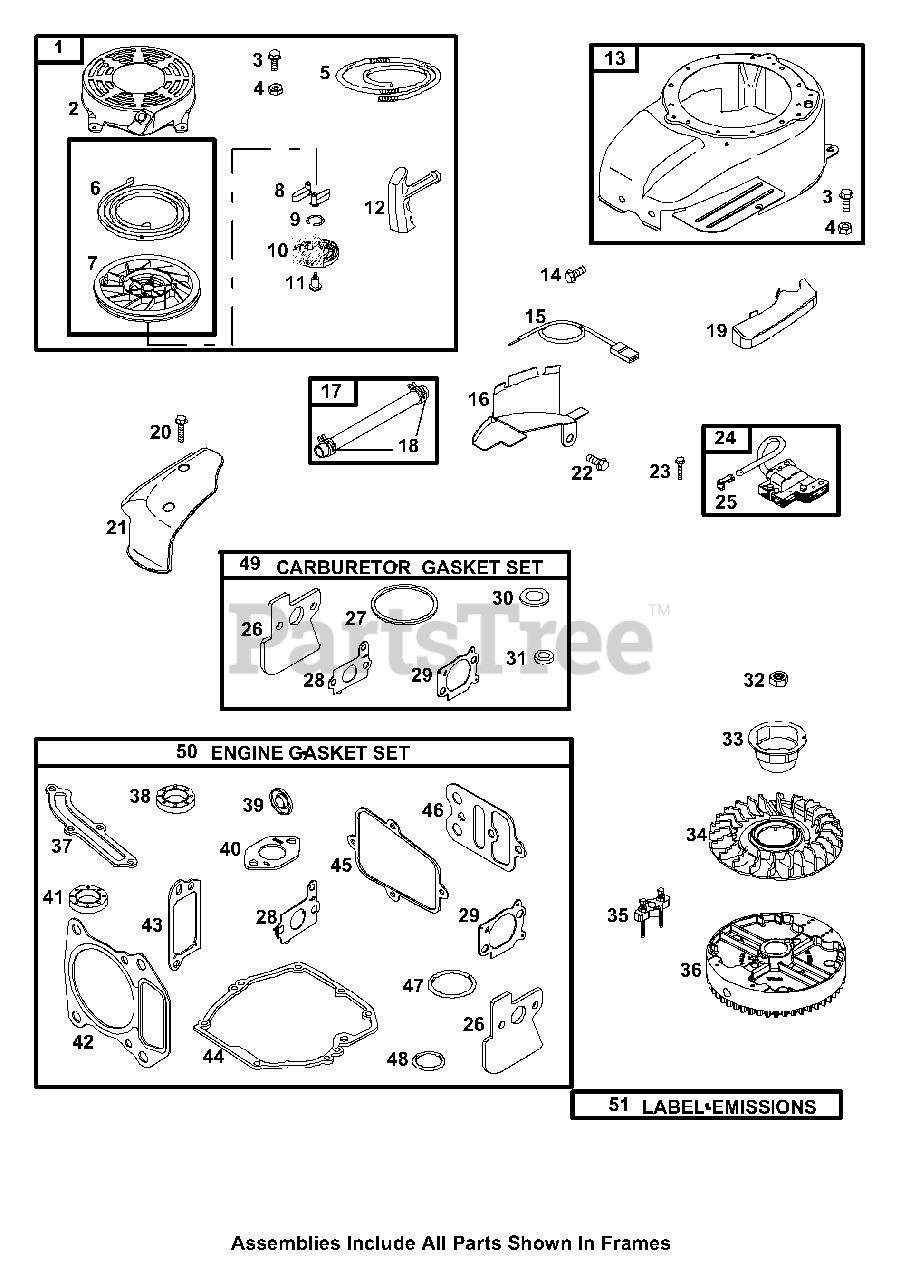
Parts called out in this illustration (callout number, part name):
1	Starter-Rewind
2	Housing-Rewind Starter
3	Screw (Rewind Starter)
4	Nut (Rewind Starter)
5	Rope-Starter
6	Pulley/Spring Assembly (Spring)
7	Pulley/Spring Assembly (Pulley)
8	Plate-Pawl Friction
9	Spring-Friction
10	Retainer-Spring
11	Screw (Pawl Friction Plate)
12	Grip-Starter Rope
13	Housing-Blower
14	Screw (Blowing Housing)
16	Guard-Flywheel
17	Line-Fuel
18	Clamp-Hose
19	Cover-Linkage
20	Screw (Control Cover)
21	Cover-Control
22	Screw (Flywheel Guard)
23	Screw (Magneto Armature)
24	Armature-Magneto
25	Terminal-Sparkplug
26	Spacer-Carburetor
27	Gasket-Float Bowl
28	Gasket-Intake
29	Gasket-Air Cleaner
30	Washer-Sealing
31	Seal-Choke/Throttle Shaft
32	Nut (Flywheel)
33	Cup-Flywheel
34	Fan-Flywheel
35	Flywheel Puller
37	Gasket-Breather Passage
38	Seal-Oil (PTO Side)
39	Seal-Valve
40	Gasket-Exhaust
41	Seal-Oil (Magneto Side)
42	Gasket-Cylinder Head
43	Gasket-Breather
44	Gasket-Crankcase
45	Gasket-Rocker Cover
46	Cylinder Head Plate Gasket
47	O-Ring Seal (Dipstick)
48	O-Ring Seal (Dipstick Tube)
49	Gasket Set-Carburetor
50	Gasket Set-Engine
51	Label-Emissions
